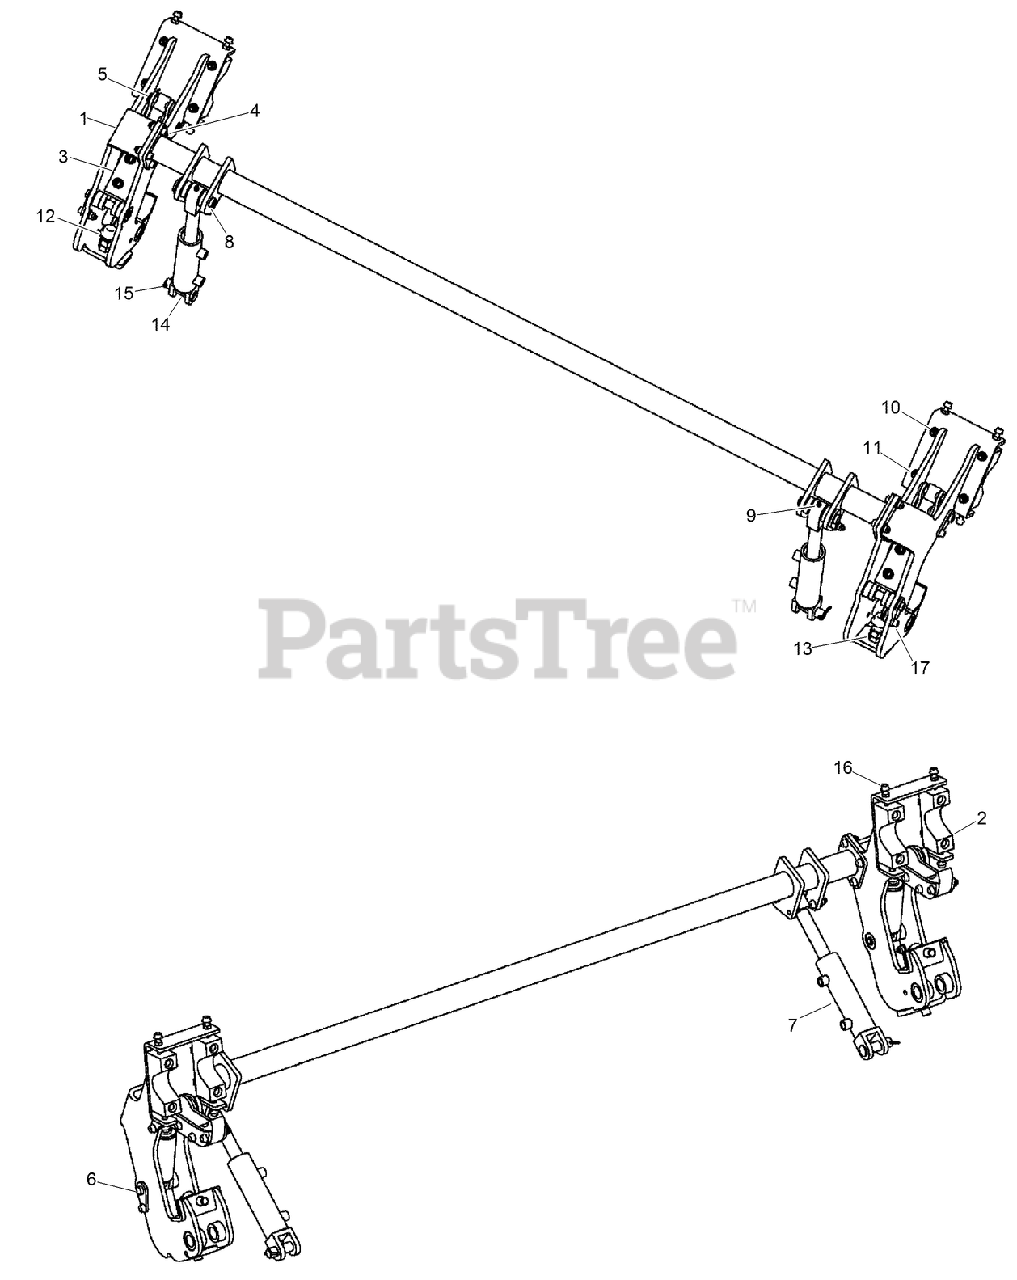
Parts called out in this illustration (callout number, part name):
1	WELDMENT - Spindle Rod Loader
2	HOLDER-PIPE
3	HYD CYLINDER ASM
4	ASSEMBLY - Gripper
5	PIN-CLEVIS
6	PIN-PIVOT (W/ FLAG)
7	CYLINDER ASM
8	PIN-PIVOT
9	FITTING-Lube 1/4-28 Tpr SAE-LT .54 Long
10	NUT-TORQUE, PREVAILING
11	SCREW-FLANGE
12	SCREW-HH
13	NUT - M16 Class 10 ZND
14	PIN - 0.75 x 2.50 Clevis
15	PIN-cotter, 5/32 x 1-3/4 inch
16	SCREW, METRIC FLANGE FULL - M8 x 35
17	SCREW-HHF
